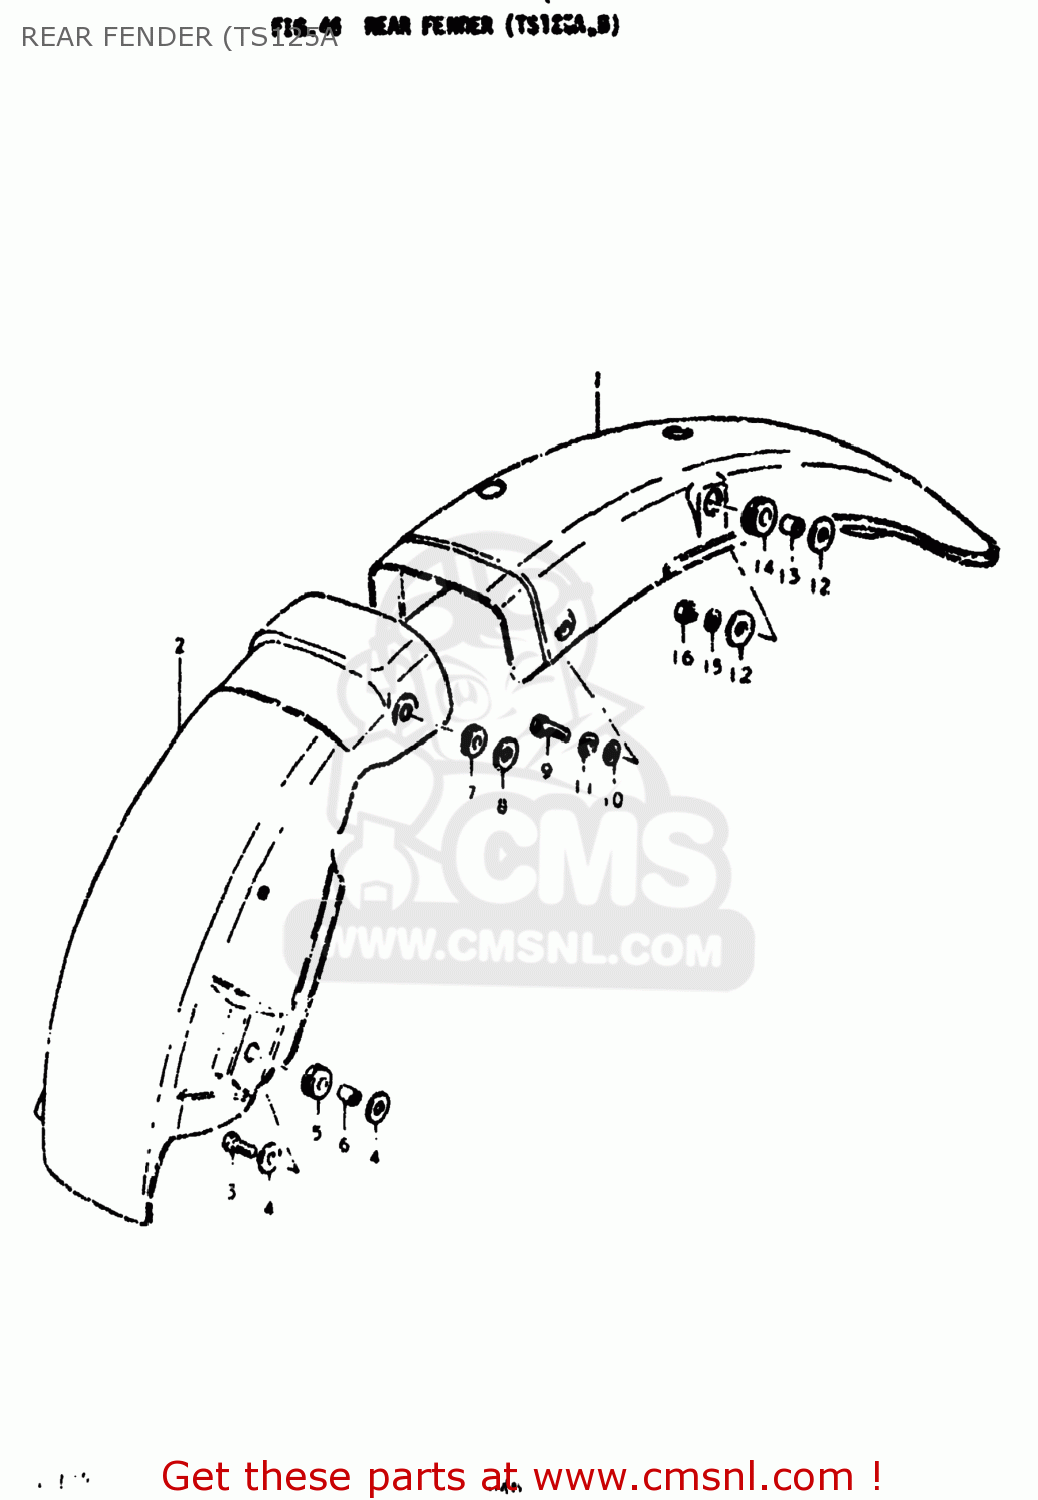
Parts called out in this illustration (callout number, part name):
1	FENDER,REAR
2	FENDER,REAR
3	BOLT
4	WASHER (6.5X20X1.2)
5	CUSHION
6	SPACER(6.1X9X7.5)
7	CUSHION
8	WASHER
9	BOLT
10	WASHER
11	LOCK WASHER
12	WASHER(10.3X25X1.5
13	SPACER
14	CUSHION
15	LOCK WASHER
16	NUT
